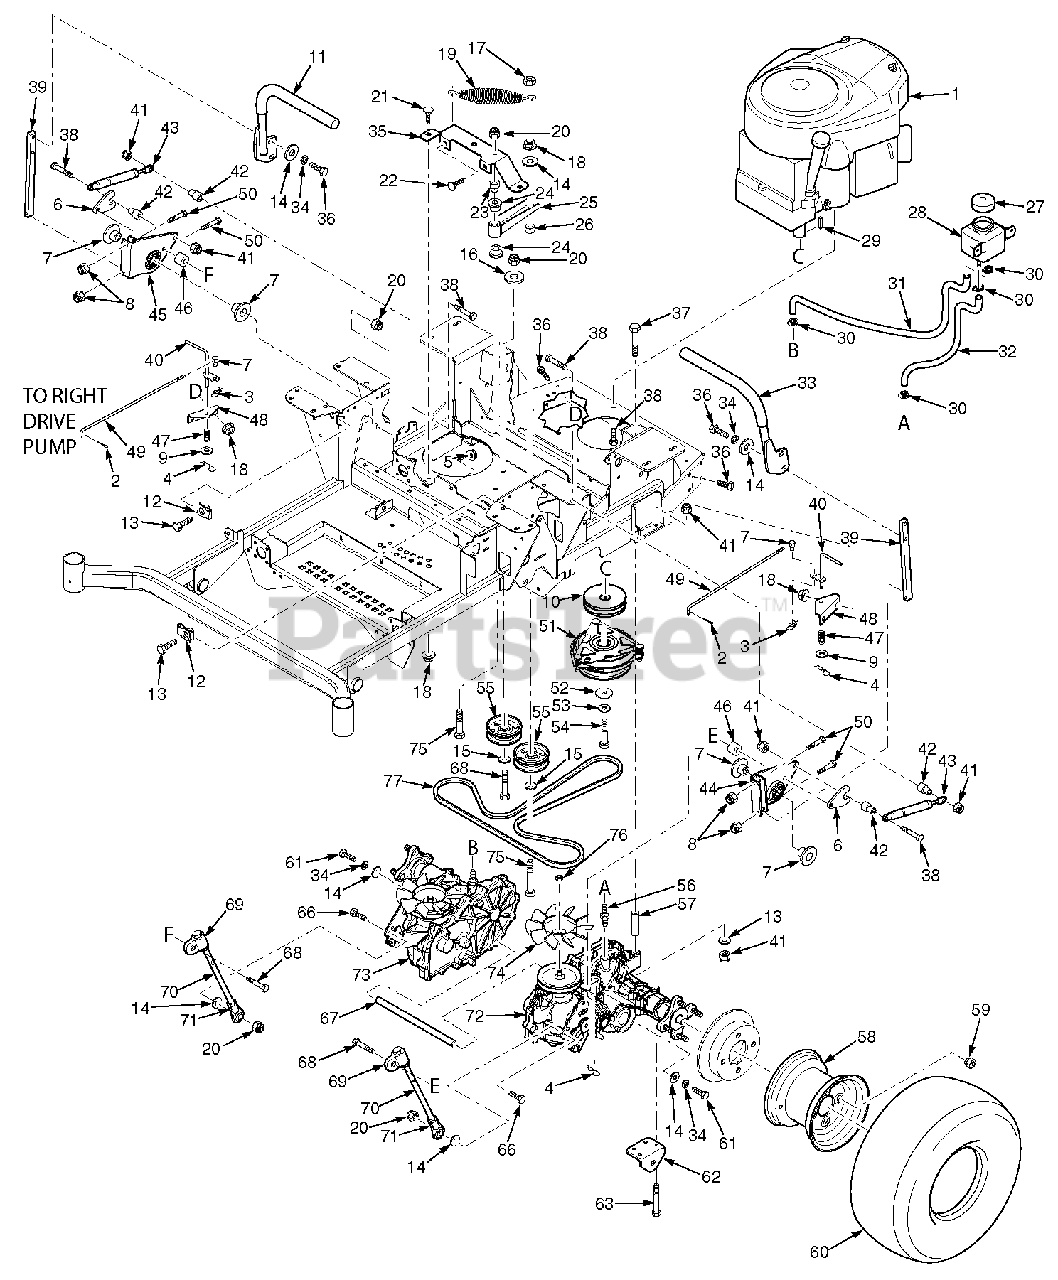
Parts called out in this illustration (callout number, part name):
1	Engine, Kawasaki - 22FX
1	Engine, Kawasaki - 23FX
2	Cotter Pin, 3/32 x 1"
3	Pin, Rue Cotter 3/8" Dia.
4	Hair Pin, .080 x 1.19"
5	Nut, Serrated Flange 5/16-18
6	Nut, Control Link
7	Spacer, Linkage
8	Nut, Elastic Stop 1/4-20
9	Flatwasher, 1/4-.312 x .750 x .065
10	Pulley, 4-1/2" OD - 1.125 Bore (SPZ52)
10	Pulley, 5" OD - 1.125 Bore (SPZ61)
11	Handle Bar w/Grip
12	U-Nut, 3/8-16
13	Bolt, Hex Head 3/8-16 x 1-1/4" Special Lock
14	Flatwasher, 3/8-.391 x .938 x .105
15	Flatwasher, 3/8-.391 x .938 x .105 HD
16	Flatwasher, 3/8-.406 x 1.5 x 7 GA.
17	Nut, Center Lock 3/8-16
18	Nut, Serrated Flange 3/8-16
19	Spring, Transmission Idler
20	Nut, Elastic Stop 3/8-16
21	Bolt, Carriage 3/8-16 x 3/4"
22	Bolt, Carriage 5/16-18 x 3/4"
23	Shaft Pivot, Idler Arm
24	Bearing
25	Transmission Idler Arm Assembly
26	Spacer, Idler Pulley - SPZ52
26	Spacer, Idler Pulley - SPZ61
28	Reservoir Assembly
29	Key, 1/4 x 1/4 x 2-3/4"
30	Clamp, 0.87" Max Dia.
31	Hose, RH Transmission
32	Hose, LH Transmission
33	Handle Bar Assembly, w/Grip
34	Lockwasher, 3/8" Spring
35	Support, Idler Arm
36	Bolt, Hex Head 3/8-16 x 1"
37	Bolt, Hex Head 5/16-18 x 5"
38	Bolt, Hex Head 5/16-18 x 1-1/2"
39	Bar, Control Lever
40	Dump Valve Lever
41	Nut, Elastic Stop 5/16-18
42	Spacer, Pump Dampener
43	Dampener
44	Control Link, LH
45	Control Link, RH
46	Spacer
47	Spring
48	Bracket, Dump Mounting
49	Linkage, Dump Valve
50	Bolt, Hex Head 1/4-20 x 1-1/2"
51	Electric Clutch Assembly - SPZ52 & SPZ61
52	Flatwasher, 7/16-.469 x 1.75 x .25
53	Lockwasher, 7/16" spring
54	Bolt, Hex Head 7/16-20 x 1-1/2" Patch SPZ-61
55	Pulley, 3-1/2" Dia.
56	Fitting, Transmission - SPZ52
56	Fitting, Transmission - SPZ61
57	Spacer, Axle - SPZ52
57	Spacer, Axle - SPZ61
58	Rim w/Valve Stem (52)
58	Rim w/Valve Stem (61)
59	Wheel Nut, 1/2-20
60	Wheel Assembly, 22 x 10.5-12 (SPZ52)
60	Tire, 22 x 10.5-12 (SPZ52)
60	Rim (SPZ52)
60	Wheel Assembly, 24 x 12-12 (SPZ61)
60	Tire, 24 x 12-12 (SPZ61)
60	Rim (SPZ61)
61	Bolt, Hex Head 3/8-16 x 2-1/4"
62	Bracket, Pusharm Link
63	Bolt, Hex Head 5/16-18 x 3"
64	Clip, Brake Lever (order through Hydro-Gear)
65	Lever, Brake (order through Hydro-Gear)
66	Bolt, Hex Head 3/8-16 x 1-1/4"
67	Spacer, Axle
68	Bolt, Hex Head 3/8-16 x 2"
69	Rod End, Adjustable 3/8-24
69	Nut, Jam 3/8-24 UNF RH
70	Linkage, Pump - SPZ52
70	Linkage, Pump - SPZ61
71	Stake, Rod End Assembly
72	Transaxle Assy., LH (ZL-KCEF-3LKG-1NXX) SPZ52
72	Transaxle Assy., LH (ZS-KCEE-3LKG-11XX) SPZ61
72	Transaxle Assy., RH (ZL-GCEF-3LKG-1NXX)SPZ52
73	Transaxle Assy., RH (ZS-GCEE-3LKF-11XX)SPZ61
73	Fan (order through Hydro-Gear)
74	Bolt, Hex Head 3/8-16 x 3"
75	Fan Nut (order through Hydro-Gear)
76	Belt, Transmission Drive - SPZ52
77	Belt, Transmission Drive - SPZ61
